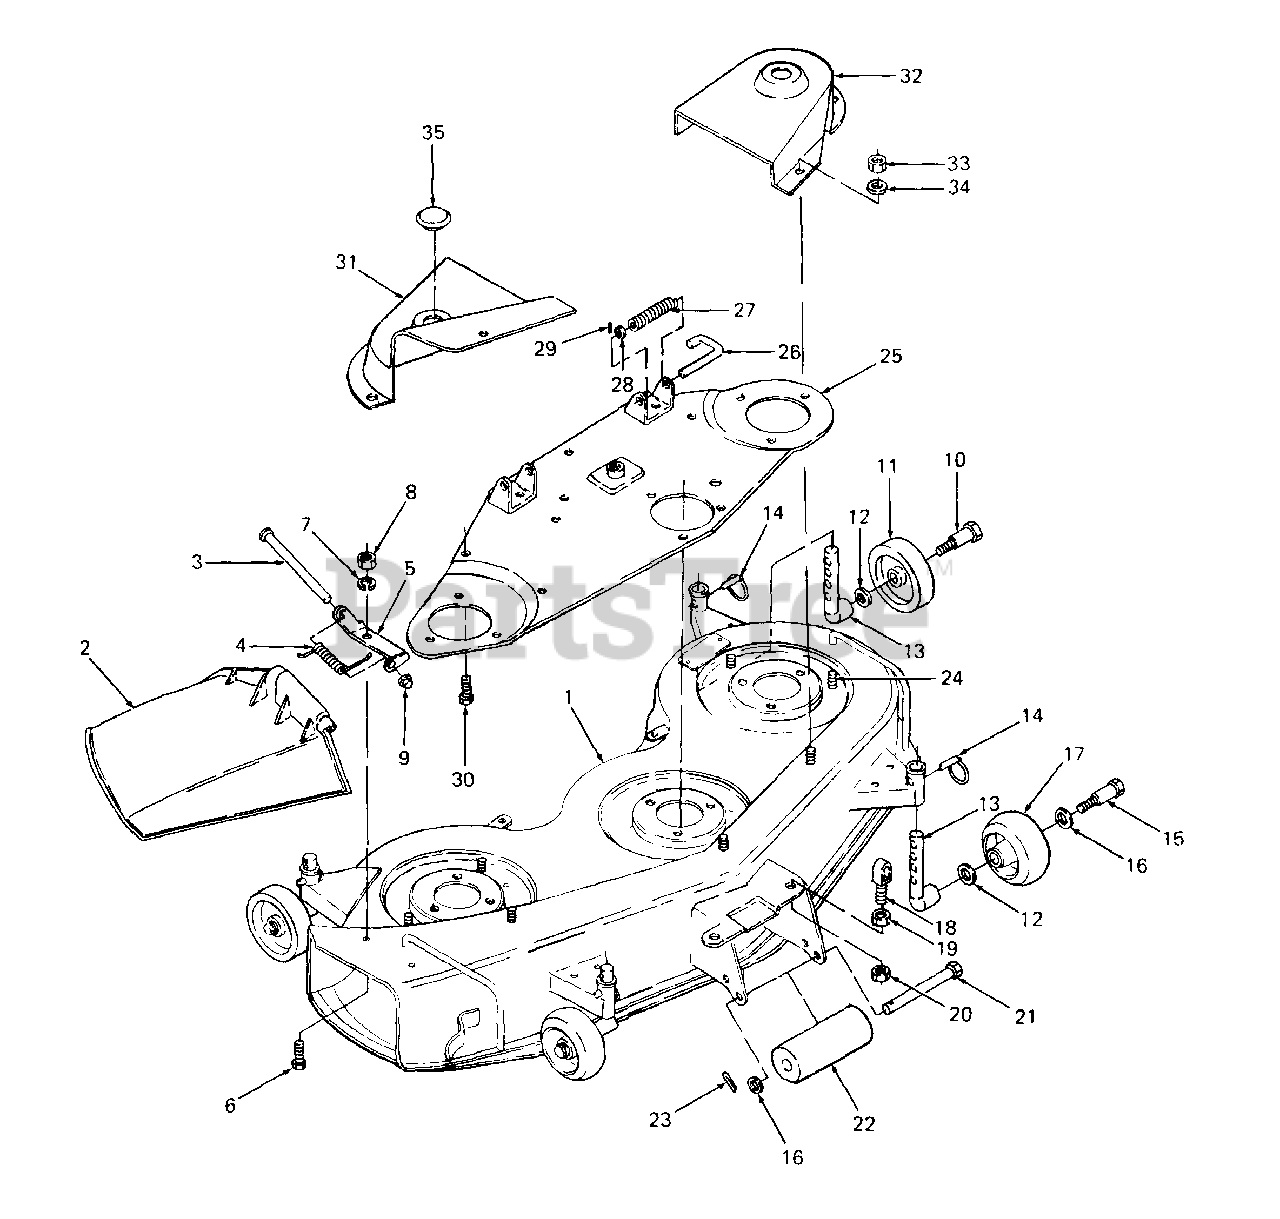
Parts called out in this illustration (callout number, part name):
2	Chute Kit w/Graphic
3	Pin, Hinge, 0.25 Dia X 6.75 Lg
4	Spring, Torsion
5	Bracket, Hinge Mtg
6	Screw, Truss Machine, 1/4-20 X .75 Lg, Phillips
7	Washer, Lock, 1/4 Dia
8	Nut, Hex, 1/4-20 GR5
9	Nut, Cap Speed
10	Screw, Shoulder
11	Wheel, Gauge, 5 in. Dia
12	Washer, Bell
13	Axle, Deck
14	Pin, Clevis w/Detent Ball
15	Screw, Shoulder
16	Washer, Flat, .510 X 1.0 X .06 Thk
17	Wheel, Ball w/Fitting, 5 in. DIA
18	Hanger, Front Mower Support
19	Nut, Hex Jam, 5/8-11 GR5
20	Nut, Hex Insert Top Lock, 5/8-11 GR5
21	Pin, Clevis, 1/2 Dia X 7.0 Lg
22	Roller, Front
23	Pin, Cotter, 3/16 Dia X 1.0 Lg
24	Screw, Hex Cutting, 5/16-18 X .75 Lg
25	Plate, Adapter
26	Pin, Mower Support
27	Spring, Compression
28	Washer, Flat, .531 X .930 X .050 Thk
29	Pin, Spirol Spring, 3/16 Dia X .75 Lg
30	Screw, Hex Cutting, 5/16-18 X .75 Lg
31	Cover, Belt RH (White)
32	Cover, Belt LH (White)
33	Nut, Hex, 5/16-18 GR5
34	Washer, Flat, .34 X .88 X .062 Thk
35	Plug, Button
